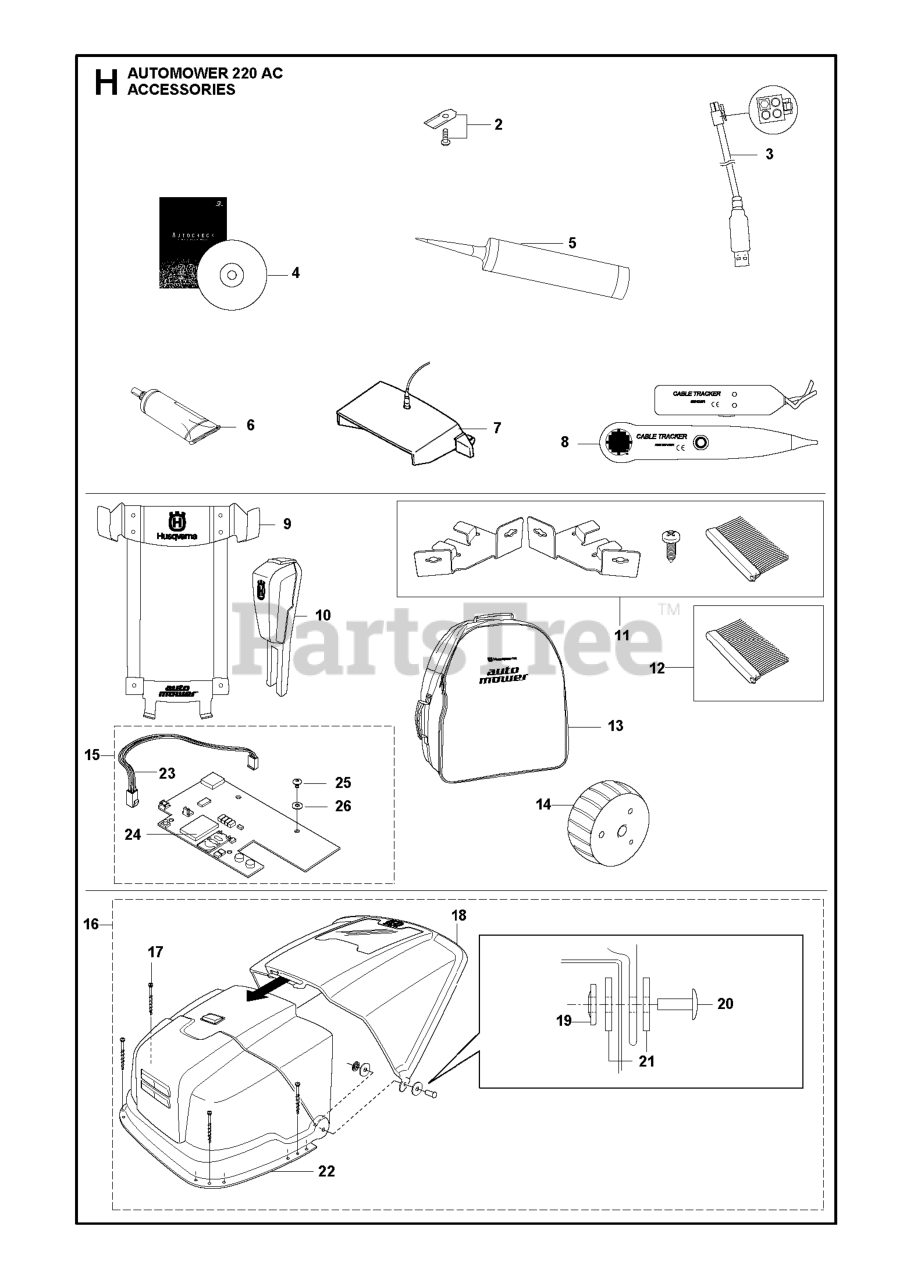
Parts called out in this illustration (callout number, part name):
2	BLADE SET 300 PCS. CARBON STEE
2	BLADE SET 45 PCS
2	BLADE KIT HUSQVARNA 9 PCS 50HR
3	USB SERVICE CABLE
4	DVD AUTOCHECK EXP SERVICE
5	GREASE 300 ML
6	GREASE OKS 110 85ML
7	N/A PIN CODE TRANSFER UNIT ADA
8	TEST EQUIPMENT
9	WALL BRACKET ASSY
10	SIGNAL BOOSTER
11	BRUSH KIT
11	BRUSH KIT BRUSH X6, HOLDER X2,
12	BRUSH KIT
14	WHEEL ASSY
14	HEAVY FRONT WHEEL KIT INCL PAC
16	AUTOMOWER SHELTER
17	SCREW KIT CS
18	TOP INCL LOGO & WINDOW CHARG
19	LOCK WASHER
20	AXLE CHARGING STATION COVER
22	FRONT CHARGING STATION COVER
23	LOOM LOOM GPS TRACKING MODULE
24	BATTERY GPS TRACKING COMMUNICA
25	SCREW GSM- MODULE
26	WASHER GSM- MODULE
